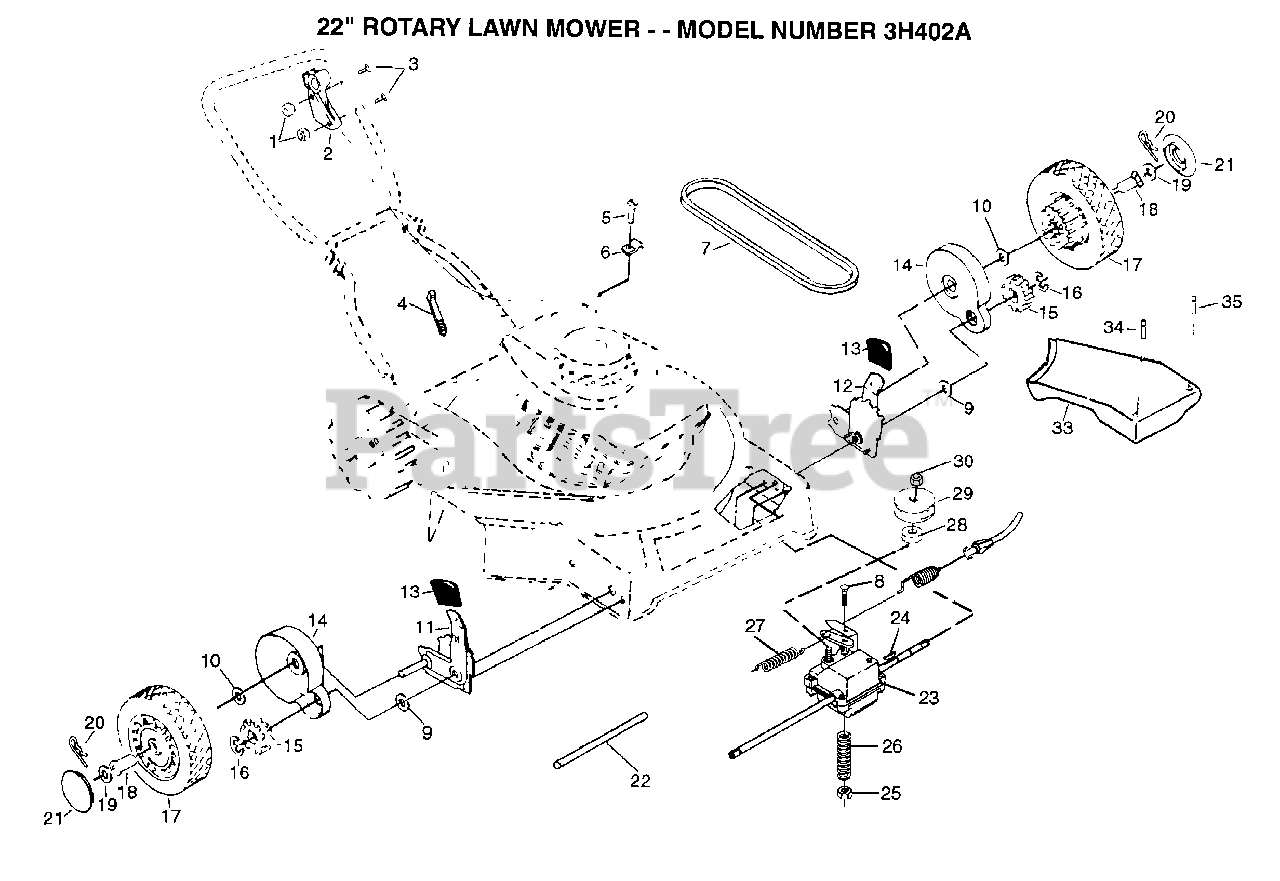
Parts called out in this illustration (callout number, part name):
2	CONTROL.DRIVE
3	SCREW
5	TAPPING SCREW
6	GUIDE CLIP PM
8	BOLT.1/4-20X2.0
9	WASHER PM
10	WASHER FLUT
13	KNOB PM
14	DUST SHROUD PM
15	PINION.GEAR
17	WHEEL.8X2.LP.PR
18	BUSHING.ROUND
19	WASHER
20	RETAINER CLIP PM
21	HUB CAP
22	DRV SHAFT TUBE PM
24	HI PRO KEY
26	SPRING.TENSION
27	SPRING
28	BEARING
29	PULLEY.DRIVEN
30	LOCKNUT
33	COVER DRIVE BLK
